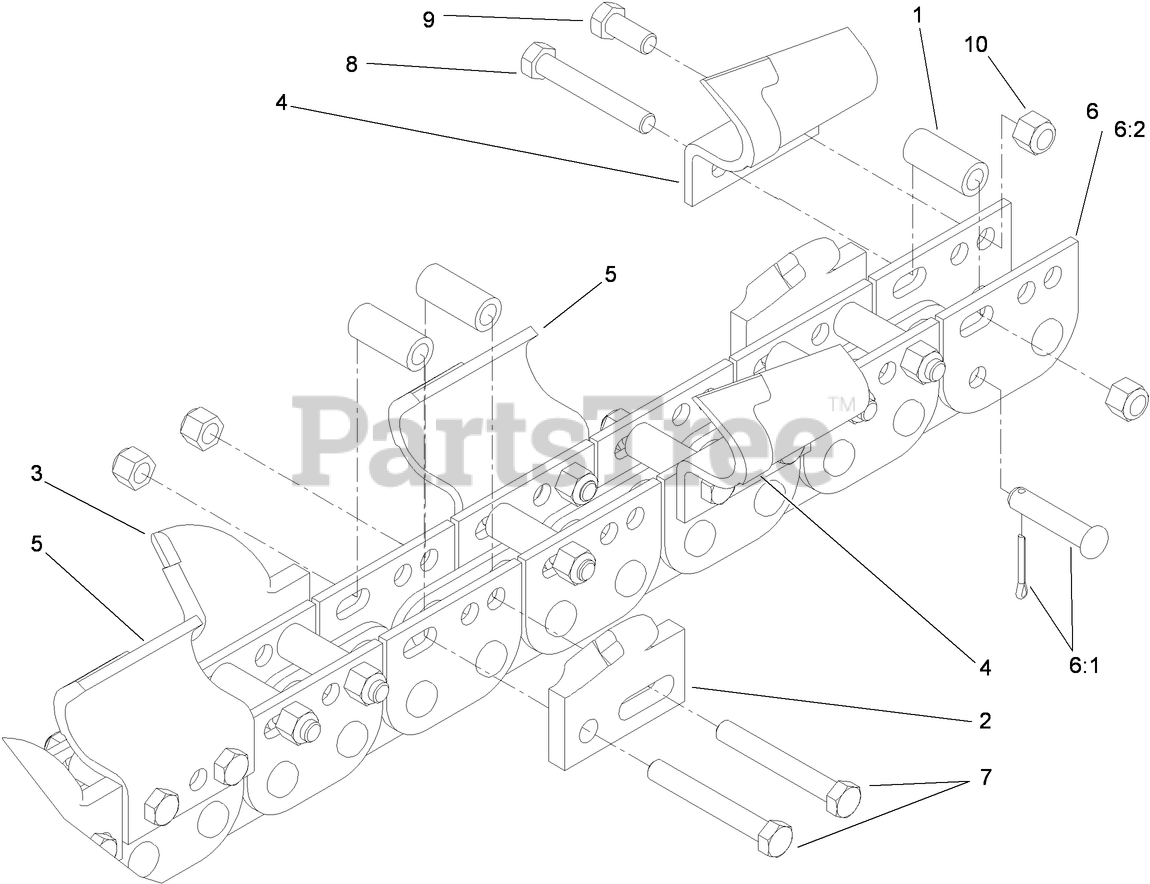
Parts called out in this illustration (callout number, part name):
1	SPACER-TUBE
2	TOOTH- ROCK, LH
3	TOOTH-ROCK, RH
4	TOOTH-SOIL, LH
5	TOOTH-SOIL, RH
6	CHAIN-BARE, 32 STATION
6:1	PIN-CONNECTING,
6:2	KIT-REPAIR, LINK
7	SCREW-HH
8	SCREW-HH
9	SCREW-HH
10	NUT-LOCK
